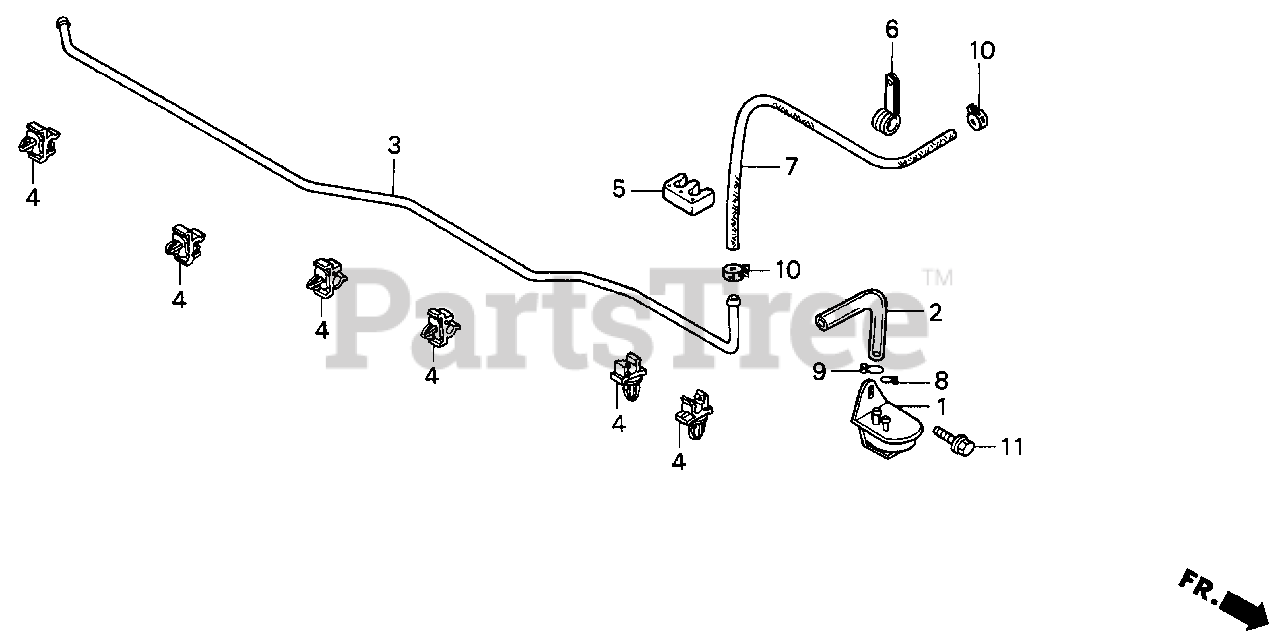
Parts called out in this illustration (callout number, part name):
1	TANK, FUEL CATCH
2	TUBE, CATCH TANK
3	PIPE, FUEL FEED
4	CLAMP, FUEL VENT PIPE
5	CLIP, DOUBLE
6	CLIP B, FUEL HOSE
7	BULK HOSE, FUEL (4.5X3000) (4.5X480)
8	CLIP, TUBE (B8)
9	CLIP, TUBE (B12.5)
10	CLIP, TUBE (D8.5)
11	BOLT, FLANGE (8X16)
